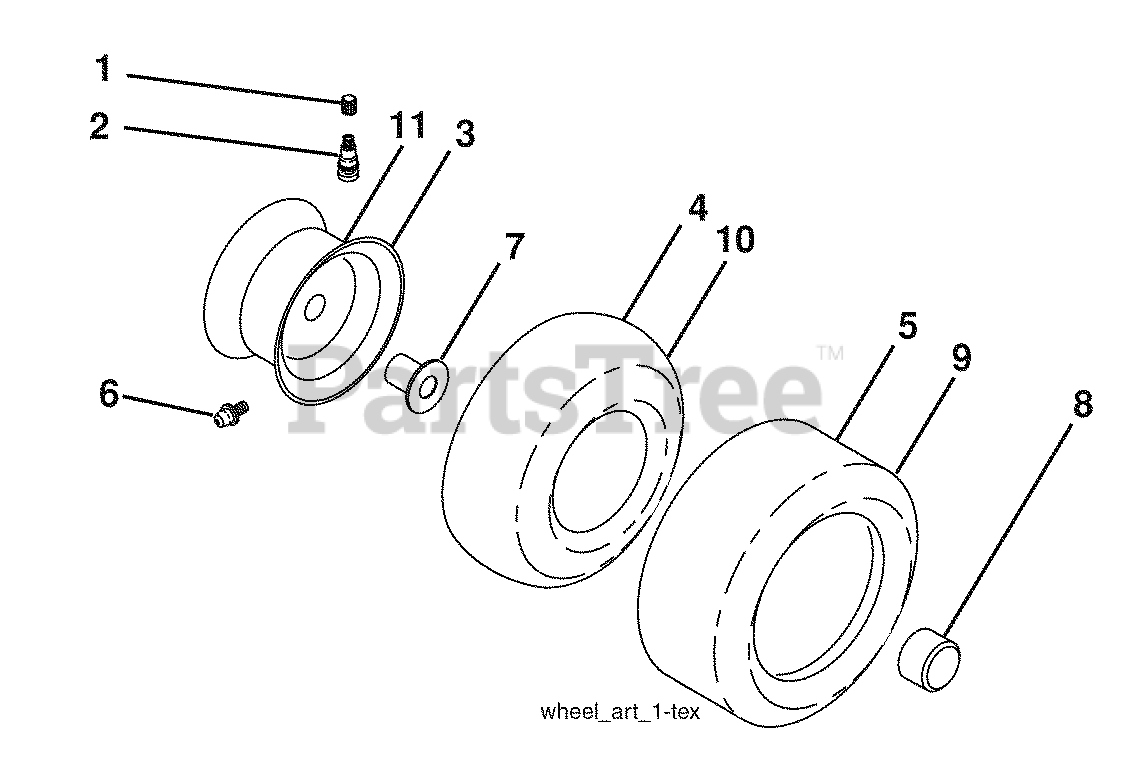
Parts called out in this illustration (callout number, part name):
2	VALVE STEM LT
3	RIM ASM 6" FRONT SILVER
4	TUBE.5.3/4.5/6
5	TIRE HEAVY DUTY
6	FITTING LT
7	BEARING T
8	CAP, AXLE BLK
9	TIRE.20X8-8.TURF.SAVER
10	TUBE
11	RIM ASM 8" REAR SILVER
